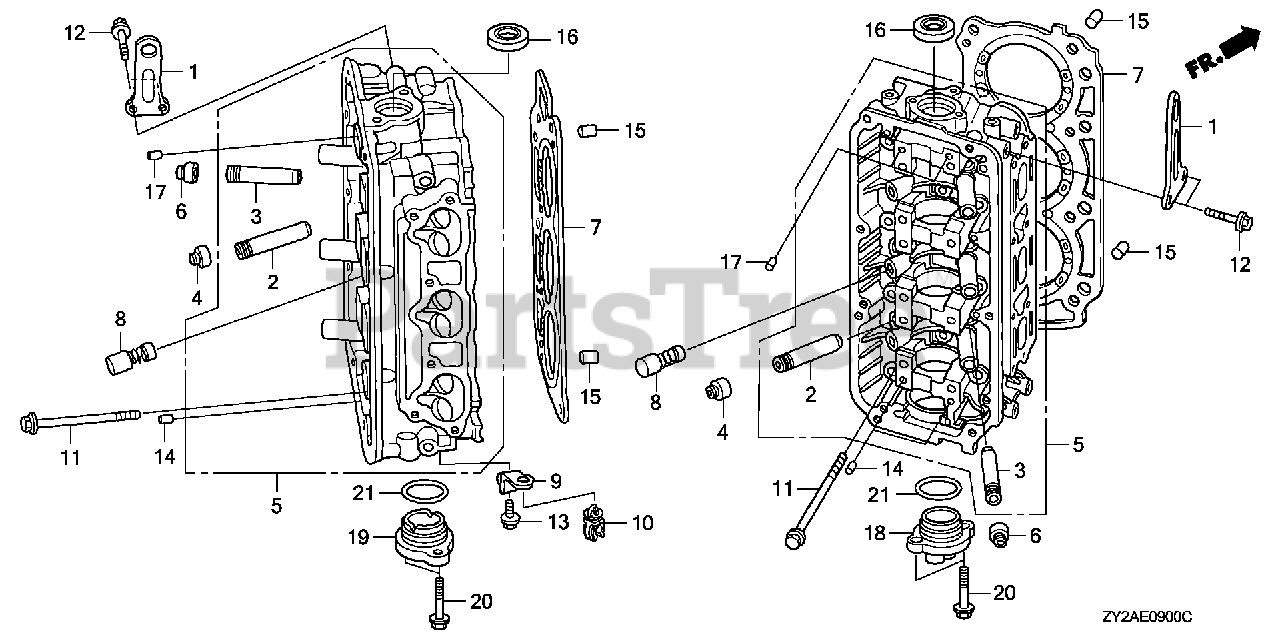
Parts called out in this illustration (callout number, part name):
1	HANGER, ENGINE
2	GUIDE, VALVE (OVER SIZE)
3	GUIDE, EX. VALVE (OVER SIZE)
4	SEAL A, VALVE STEM (NOK)
5	CYLINDER HEAD *NH8* (DARK GRAY)
6	SEAL B, VALVE STEM (NOK)
7	GASKET, CYLINDER HEAD (NIPPON LEAKLESS)
8	MOTION, LOST
9	BRACKET, FUEL TUBE
10	CLIP, THROTTLE WIRE
11	BOLT-WASHER (12X163)
12	BOLT, FLANGE (8X20)
13	BOLT, FLANGE (8X16)
14	PIN, DOWEL (6X10)
15	PIN, DOWEL (16X22)
16	OIL SEAL (39X53X8) (NOK)
17	PIN B, DOWEL (6X10)
18	COVER, R. CAMSHAFT THRUST
19	COVER, L. CAMSHAFT THRUST
20	BOLT, FLANGE (8X28)
21	O-RING (48.5X2.4)
